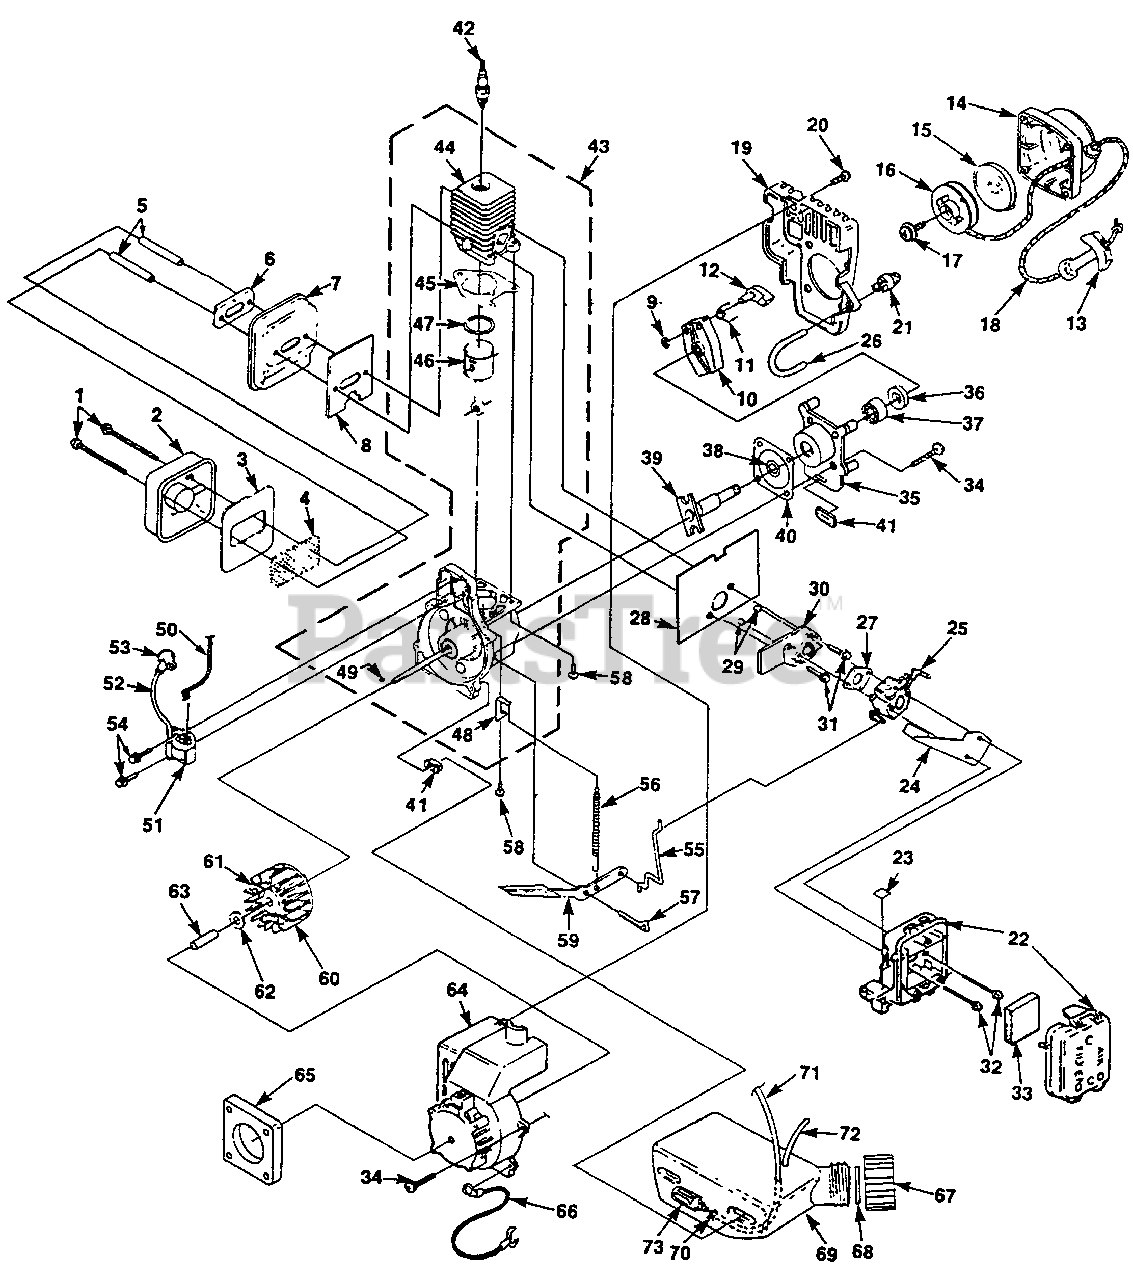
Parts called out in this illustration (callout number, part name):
1	SCREW- Sems hex hd. (10-24 x 2 1/2")
2	COVER- Muffler
3	BAFFLE- Muffler
4	SCREEN- Spark
5	SPACER- Muffler
6	PLATE- Reinforcing
7	BODY- Muffler
8	GASKET- Muffler
9	RING- Retaining
10	CUP- Starter
11	SPRING
12	PAWL- Starter
13	GRIP- Starter
14	HOUSING- Starter
15	SPRING- Recoil
16	PULLEY
17	SCREW- Set
18	ROPE- Starter
19	COWLING- Engine
20	SCREW- Truss hd. (#10 x 1/2")
21	BULB- Primer
22	AIR FILTER BOX ASSEMBLY
23	DECAL- Choke
24	BRACKET- Cable mounting
25	CARBURETOR
26	RUBBER TUBING (4")
27	GASKET- Carburetor
28	GASKET- Heat Dam
29	NUT- Hex lock (10-24)
30	HEAT DAM
31	SCREW- Thd. Forming (10-24 x 1")
32	SCREW- Truss hd.(10-24 x 2 1/4")
33	AIR FILTER
34	SCREW- Truss hd. (10-24 x 3/4")
35	COVER- Crankcase
36	SEAL-Shaft
37	BEARING- Ball
38	SPACER
39	SHAFT- Starter
40	GASKET- Crank Cover
41	BUMPER- Rubber
42	SPARK PLUG
43	SHORT BLOCK
44	CYLINDER & GASKET
45	GASKET- Cylinder
46	PISTON & ROD
47	RING- Piston
48	BRACKET- Governor Spring
49	KEY- Woodruff
50	LEAD- Electrical
51	MODULE- Ignition
53	TERMINAL
54	SCREW- Taptite (8-32 x 1")
55	ROD- Governor
56	SPRING- Extension
57	PIN- Cotter
58	SCREW- Thd. forming (10-24 x 3/4")
59	VANE- Governor
60	ROTOR & STARTER PAWL KIT
61	STARTER PAWL KIT
62	WASHER- Flat
63	SPACER
64	HOUSING
65	SPACER- Engine
66	WIRE- Ground
67	FUEL CAP
68	GASKET- Fuel cap
69	TANK- Fuel
70	CLAMP- Wire
71	TUBING- Rubber
72	TUBING- Rubber (6")
73	FILTER- Fuel
